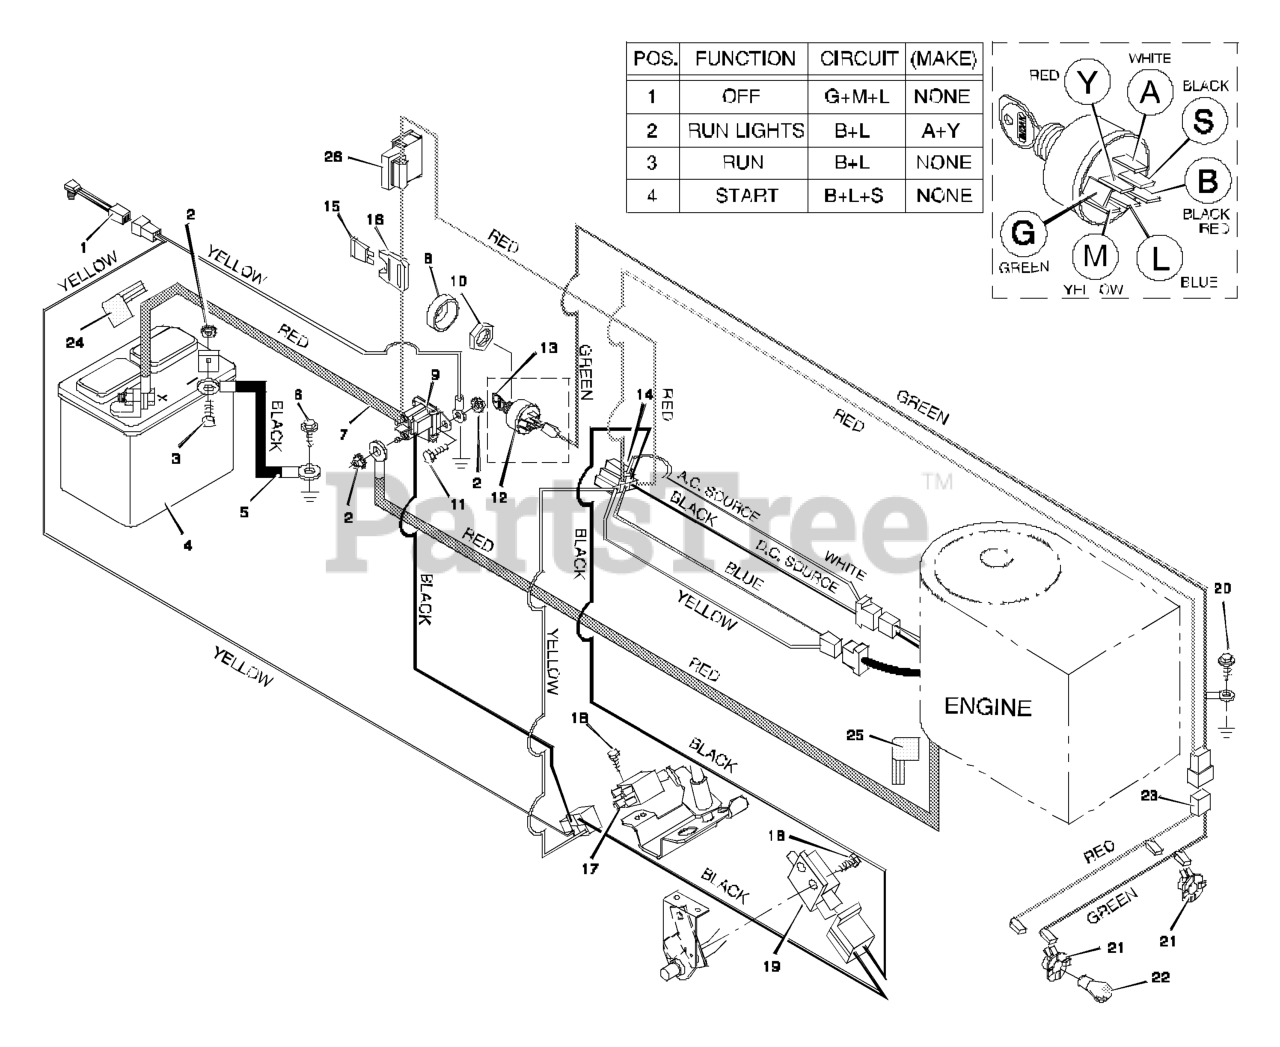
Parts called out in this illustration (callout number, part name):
1	Switch, Seat Sensor
2	Locknut
3	Bolt, Hex
4	Battery
5	Cable, Battery Ground
7	Cable, Red Battery
8	Cap, Ignition
9	Solenoid
10	Nut
12	Switch, Ignition
13	Key, Ignition
14	Harness, Chassis Wire
16	Holder, Fuse
17	Switch, Clutch
19	Switch, Clutch
20	Screw
21	Socket, Light
22	Bulb, Light
23	Harness, Light Wire
24	Cover, Terminal
26	Ammeter
